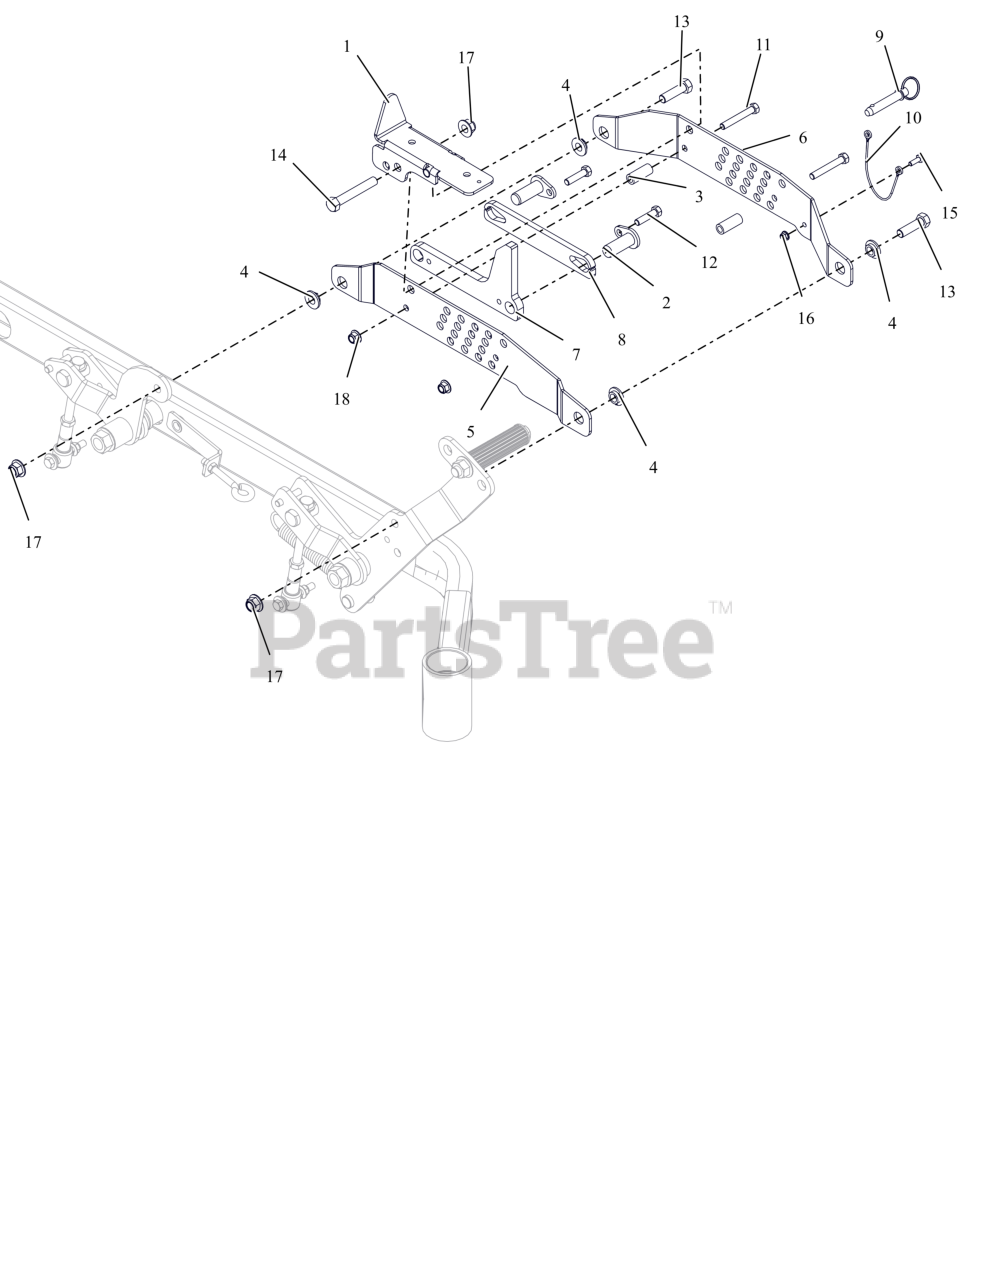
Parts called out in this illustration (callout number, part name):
1	MECHANICAL LOCK-UP WMT - BLACK
2	WLDMT, PIN HOC MOUNTING
3	SPACER, .375 X .625 X 1.54
4	BSHG-FLG .515X.750X.310X1.120
5	RH OTBRRD LIFT/CUT HT BRKT-BLK
6	RH INBRD LIFT/CUT HT BRKT- BLK
7	HOC STOP BRKT - BLK
8	HOC STOP SPACER - BLK
9	PIN, .50 X 2.00 USABLE LG BALL
10	CABLE, 12.0 LANYARD, NYLON
11	BLT, HEX .38-16X2.50 G5 ZCC
12	BLT, HEX 0.375-16X1.5 GR5 ZCC EP30
13	BLT, HEX .50-13X1.75 G5 ZCC
14	BLT,HEX .50-13X3.25 G5 ZCC
15	BLT, HEX .25-20X.75 G5 ZCC
16	NUT,NYL-FLG .25-20 GF ZCC
17	NUT,NYL-FLG .50-13 GF ZCC
18	NUT,NYL-FLG .38-16 GF ZCC
